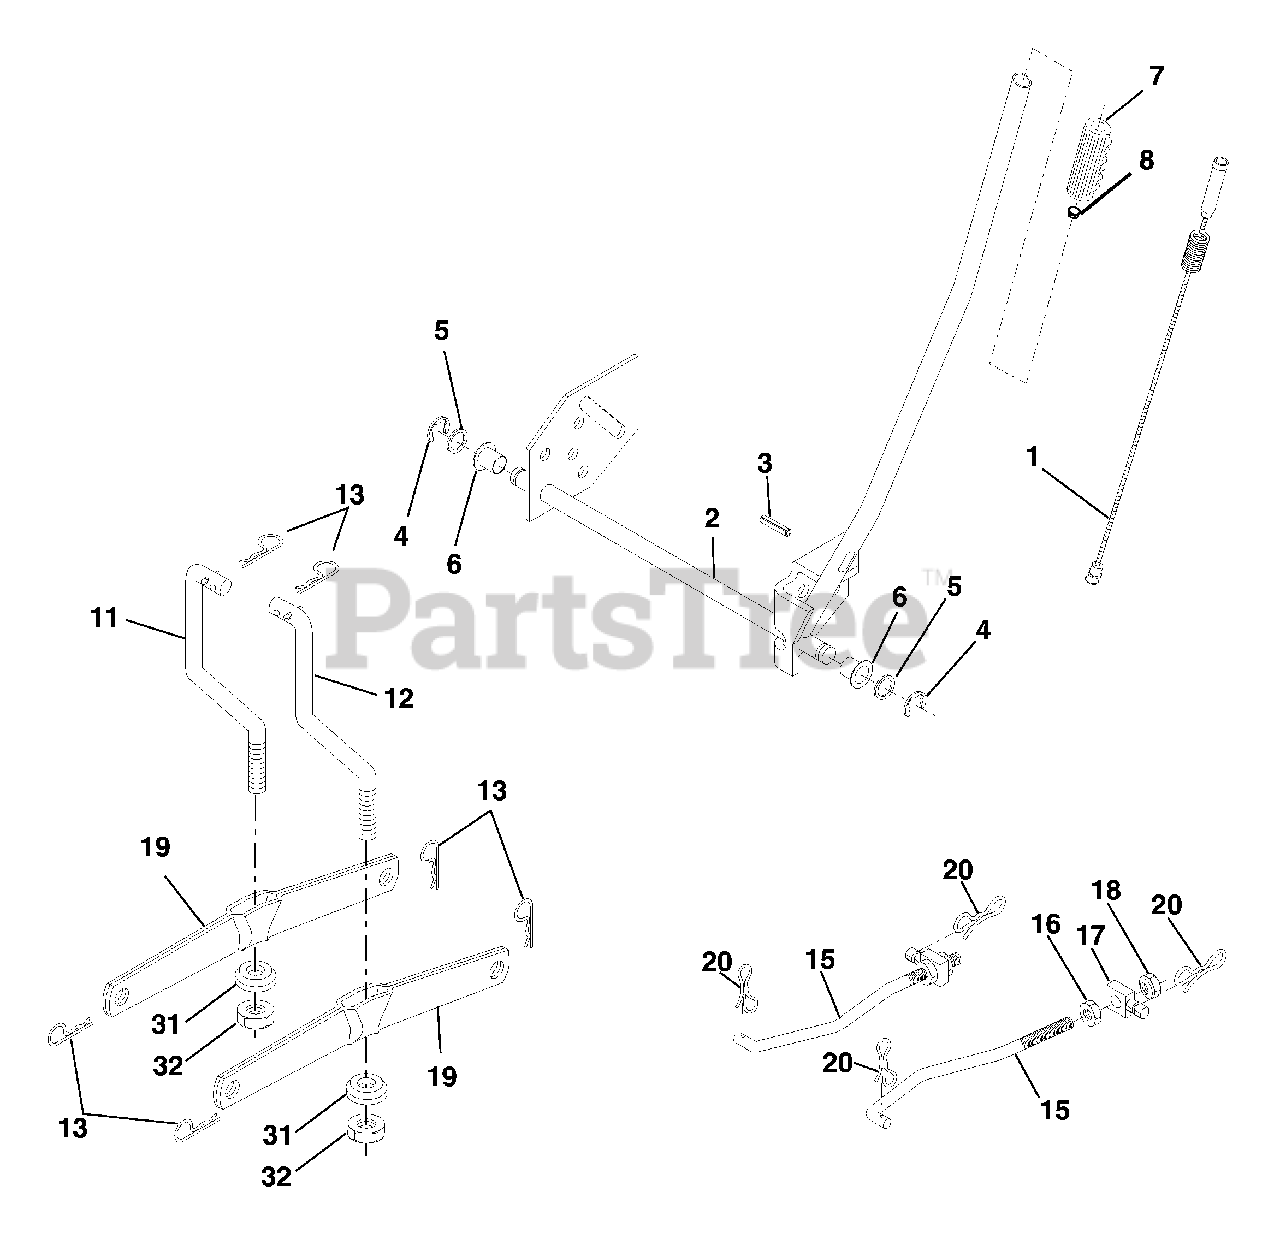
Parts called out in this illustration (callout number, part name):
1	Wire Asm Inner/Sprg W/plunger
2	Shaft Asm Lift RH w/Inf
3	Pin Groove 5/16 Dia x 1.875
4	E Ring #5133-62
5	Washer 21/32 x 1 x 21 Ga.
6	Bearing Nylon Blk 629 Id
7	Grip Handle
11	Link Lift LH Fixed Length
12	Link Lift RH Fixed Length
13	Retainer Spring
15	Link Front
16	Nut Jam Hex 1/2-13 unc
17	Trunnion
18	Nut Lock W/Wsh 1/2-13 unc
19	Arm Suspension Rear
20	Pin Cotter 7/16 Bow Tie Lock
31	Bearing Pvt Lift
32	Nut Crownlock 3/8 - 24
